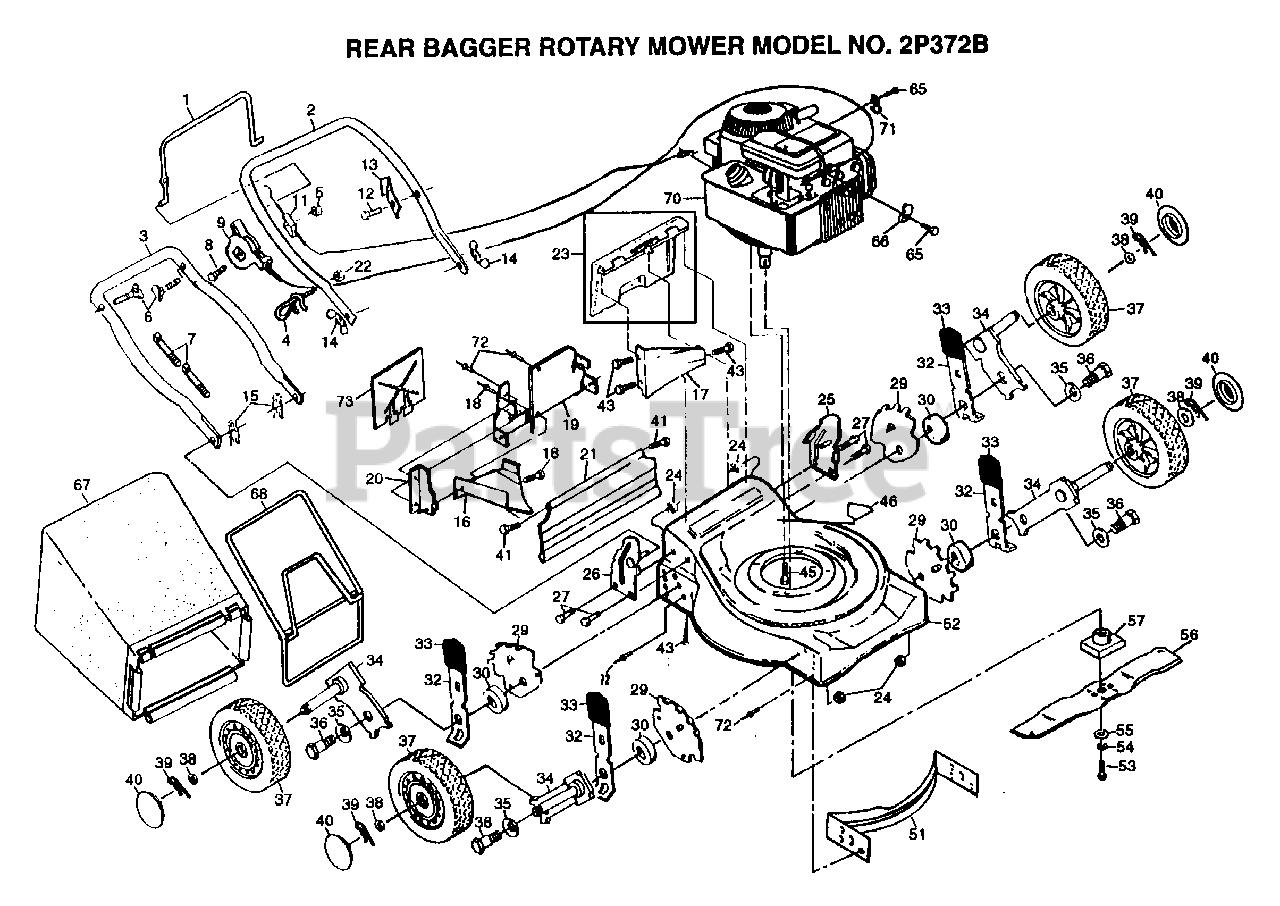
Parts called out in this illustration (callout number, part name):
1	CONTROL BAR
4	ROPE GUIDE
6	BOLT.HANDLE.LM
8	SCREW.HXHD.WASH.
9	CONTROL THROTTLE
11	"CABLE,ENG ZONE CO"
12	TAPPING SCREW
13	"BRKT,UPSTOP"
14	"NUT,WING PM"
15	HAIRPIN COTTER
16	DISCHARGE GUARD
17	REAR BAFFLE
18	SCREW PM
19	PLATE.BACK.20RD
21	SKIRT.PUSH.20RD
22	NUT
23	KIT.DOOR.RR.20STL
24	LOCKNUT PM
27	SCREW
29	BRACKET.ADJ.9POS.
32	SPRING SELECTOR
33	KNOB PM
34	AXLE ARM
35	"WASHER, BELLEVIL."
36	BOLT SHLD 3/8-16
38	WASHER
39	RETAINER CLIP PM
40	HUB CAP
41	HINGE SCREW
43	SCREW
45	SCREW
46	DECAL HYT
53	SCREW
54	LOCKWASHER
55	"WASHER,HARDEN"
57	BLADE ADAPTOR
65	SCREW PM
66	CABLE CLAMP
67	GRASS BAG
68	CATCHER FRAME
71	GUIDE CLIP PM
72	BLIND RIVET
73	MULCHER PLATE
